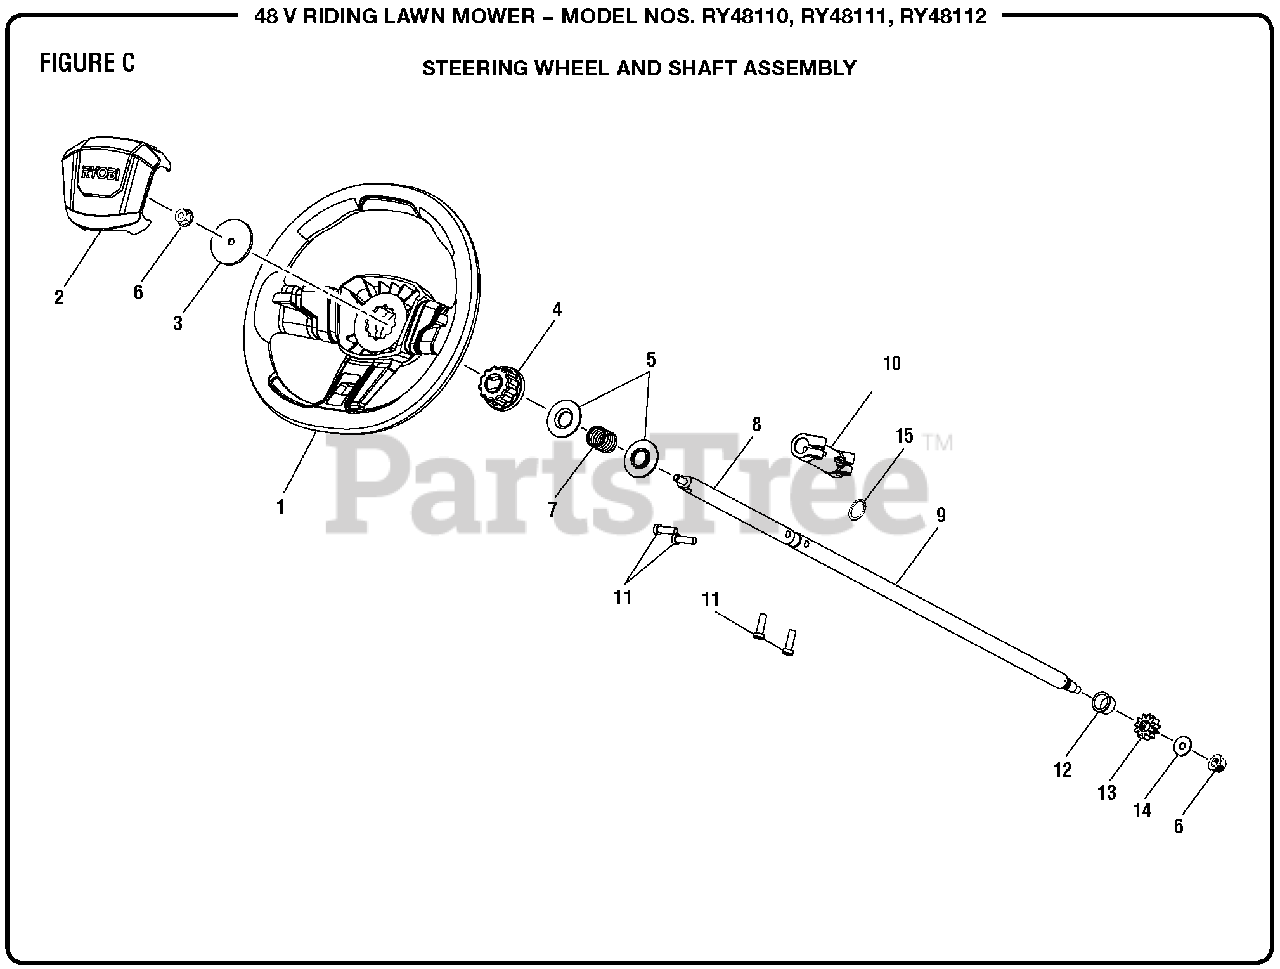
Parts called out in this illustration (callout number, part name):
1	Steering Wheel
2	Steering Wheel Cap
3	Washer Plate
4	Spline Collar
5	Spring Seat
6	Flange Lock Nut (M8)
7	Steering Shaft Spring
8	Upper Steering Shaft
9	Lower Steering Shaft
10	Steering Shaft Coupling
11	Screw (M8 x 25 mm, Soc. Hd.)
12	Flanged Bushing (19 x 22 x 15)
13	Steering Pinion Gear
14	Washer (OD24 x ID8.4 x 2t)
15	Retaining Ring
